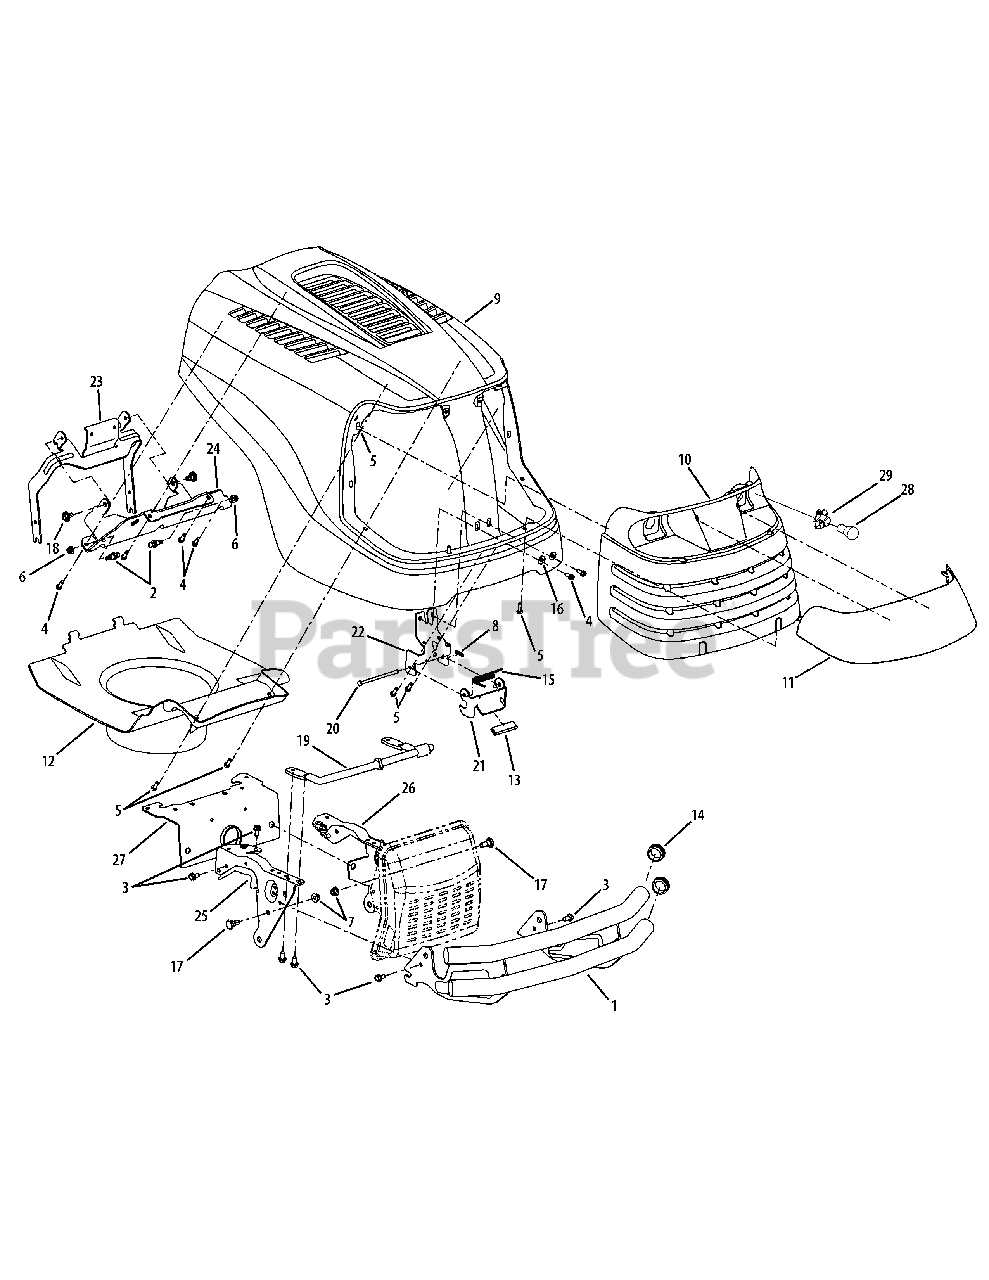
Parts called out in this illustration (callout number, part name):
2	Bolt, Ball Shoulder, 5/16-18 x .48
3	Screw, Hex, 5/16-18 x .750
4	Screw, Self Tapp, 1/4-20 x.750
5	Screw, 1/4-15 x.750
6	Nut, Flange Lock, 5/16-18
7	Nut, Nylon Lock, 3/8-16
8	Pin, Cotter,.072 Dia. x 1.13
9	Hood, Service Kit
9	Hood
9	Push Nut .25ID x .50 OD
9	Screw, Hi Low 5/16-14 x .75
10	Grill
11	Lens
12	Hood Plenum
13	Vinyl Strip, 2.5"
14	Cap, Bumper
15	Latch Spring
16	Washer, Flat, .28 x .74 x .063
17	Screw, Shoulder, 3/8-16
18	Screw, Shoulder, 5/16-18
19	Hood Latch Rod
20	Rod,.250 Dia. x 4.55
21	Latch Pivot Bracket
22	Latch Plate
28	Miniature Lamp, 12V
29	Lamp Socket
